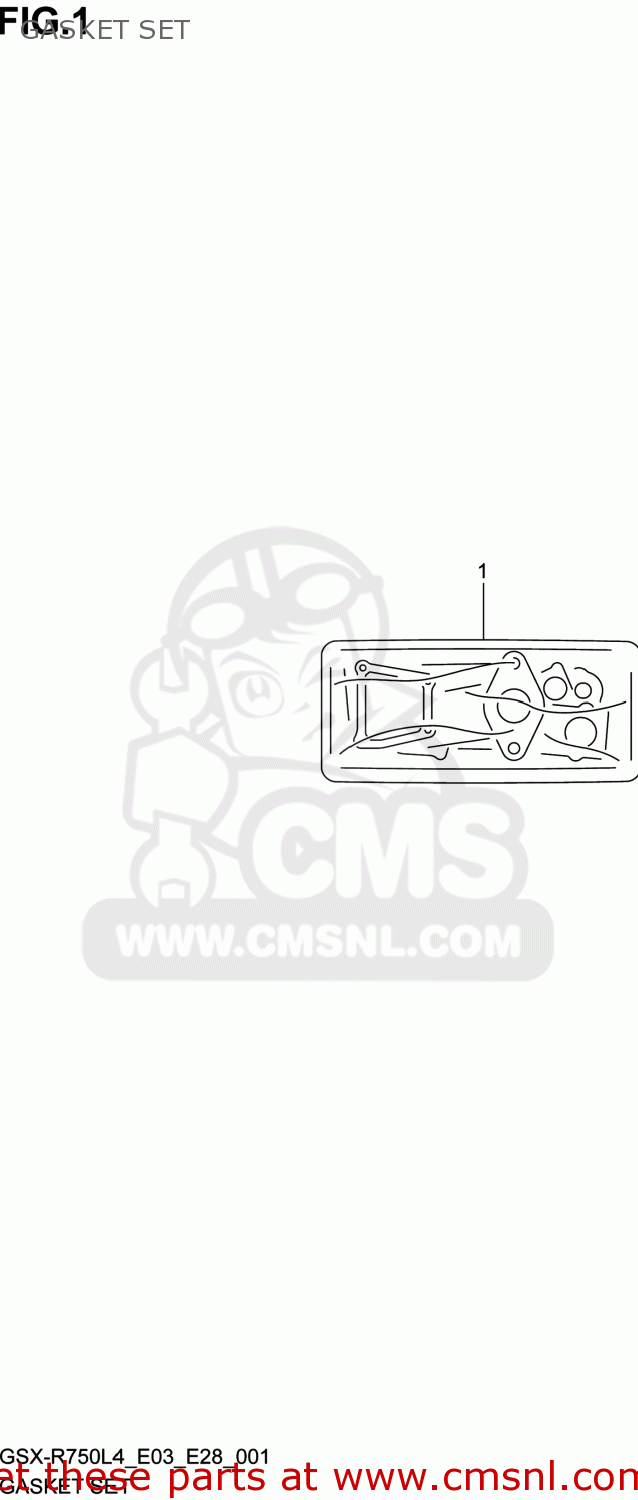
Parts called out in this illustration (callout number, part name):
1	GASKET SET (NAS)
2	GASKET,CYLINDER HEAD (NAS)
3	GASKET,CYL HEAD COVER NO.1 (NAS)
4	GASKET,CYL HEAD COVER NO.2 (NAS)
5	WASHER,CYL HEAD COVER
6	GASKET,CLUTCH COVER (NAS)
7	GASKET,GENERATOR COVER (NAS)
8	GASKET,BREATHER COVER (NAS)
9	GASKET,OIL PAN(ASB) (NAS)
10	GASKET,TENSIONER ADJUSTER (NAS)
11	GASKET,EXHAUST PIPE
12	O RING(D:2.4,ID:15.8)
13	O RING(D:3.1,ID:16.8)
14	O RING(D:2.4,ID:24.7)
15	O RING(D:3.1,ID:32.7)
16	O RING(D:2.6,ID:67.1)
17	O RING,FUEL PUMP
